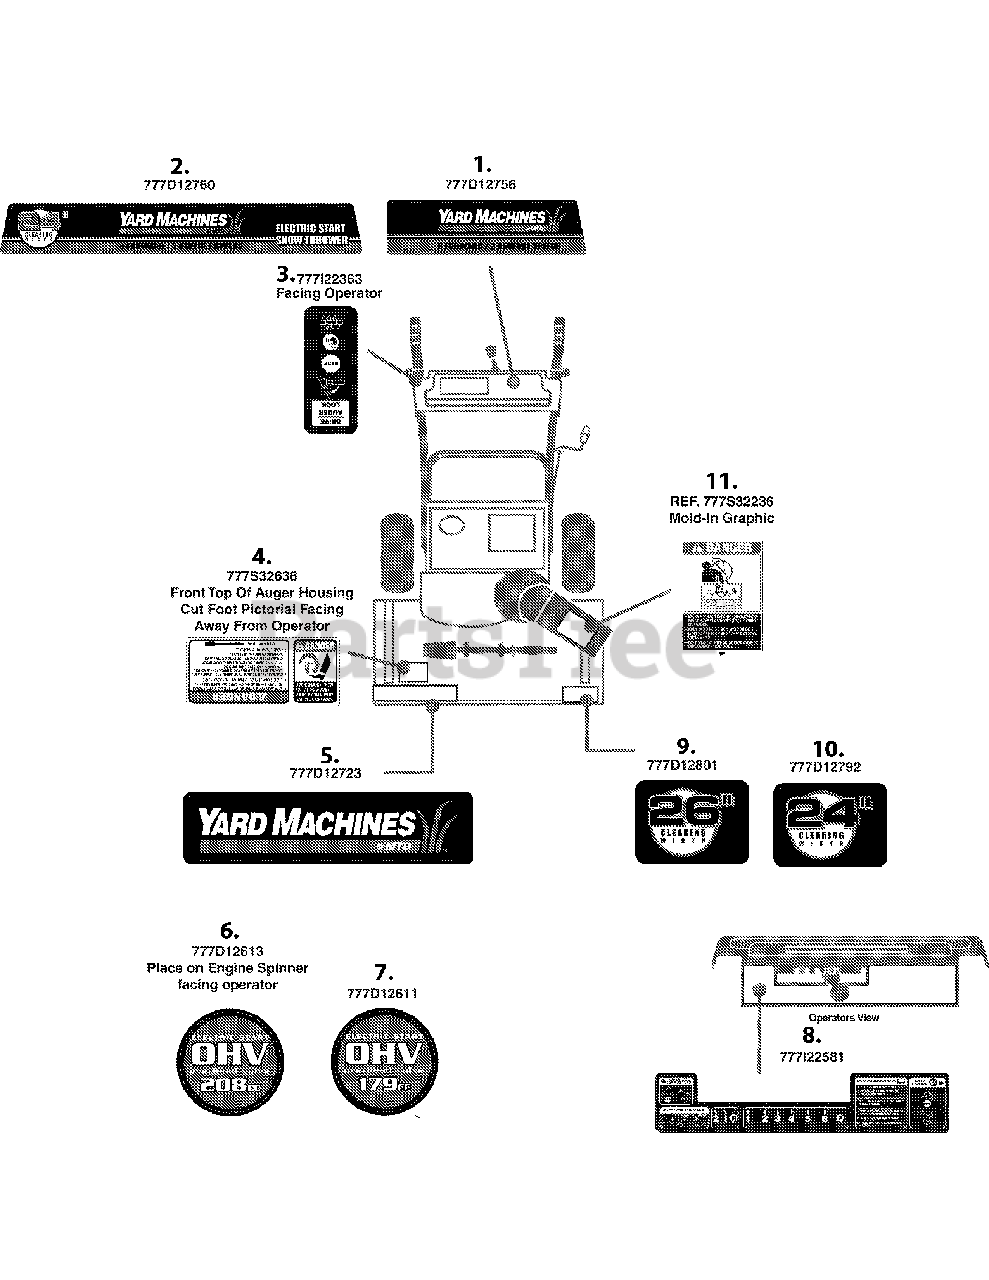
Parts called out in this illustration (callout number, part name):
1	LABEL:SNOW:FRT/HNDL/PAN:YM:6/2
2	LABEL:SNOW:HNDLPANL:YMACH:24/6/2
3	LABEL:DRV/AUGR LOCK
4	LABEL:SNOW HOUSING
5	LABEL:SNOW:FRNT/LFTAUG:YMACH/BLK
6	LABEL:ENG/SPN:OHV/ES/208
7	LABEL:ENG/SPN:OHV/ES/179
8	LABEL:OPERATOR PAN
9	LABEL:SNOW:FRNT/RTAUG:YM/BLK:26
10	LABEL:SNOW:FRNT/RTAUG:YMACH:24/BL
11	LABEL:SNOW CHUTE
